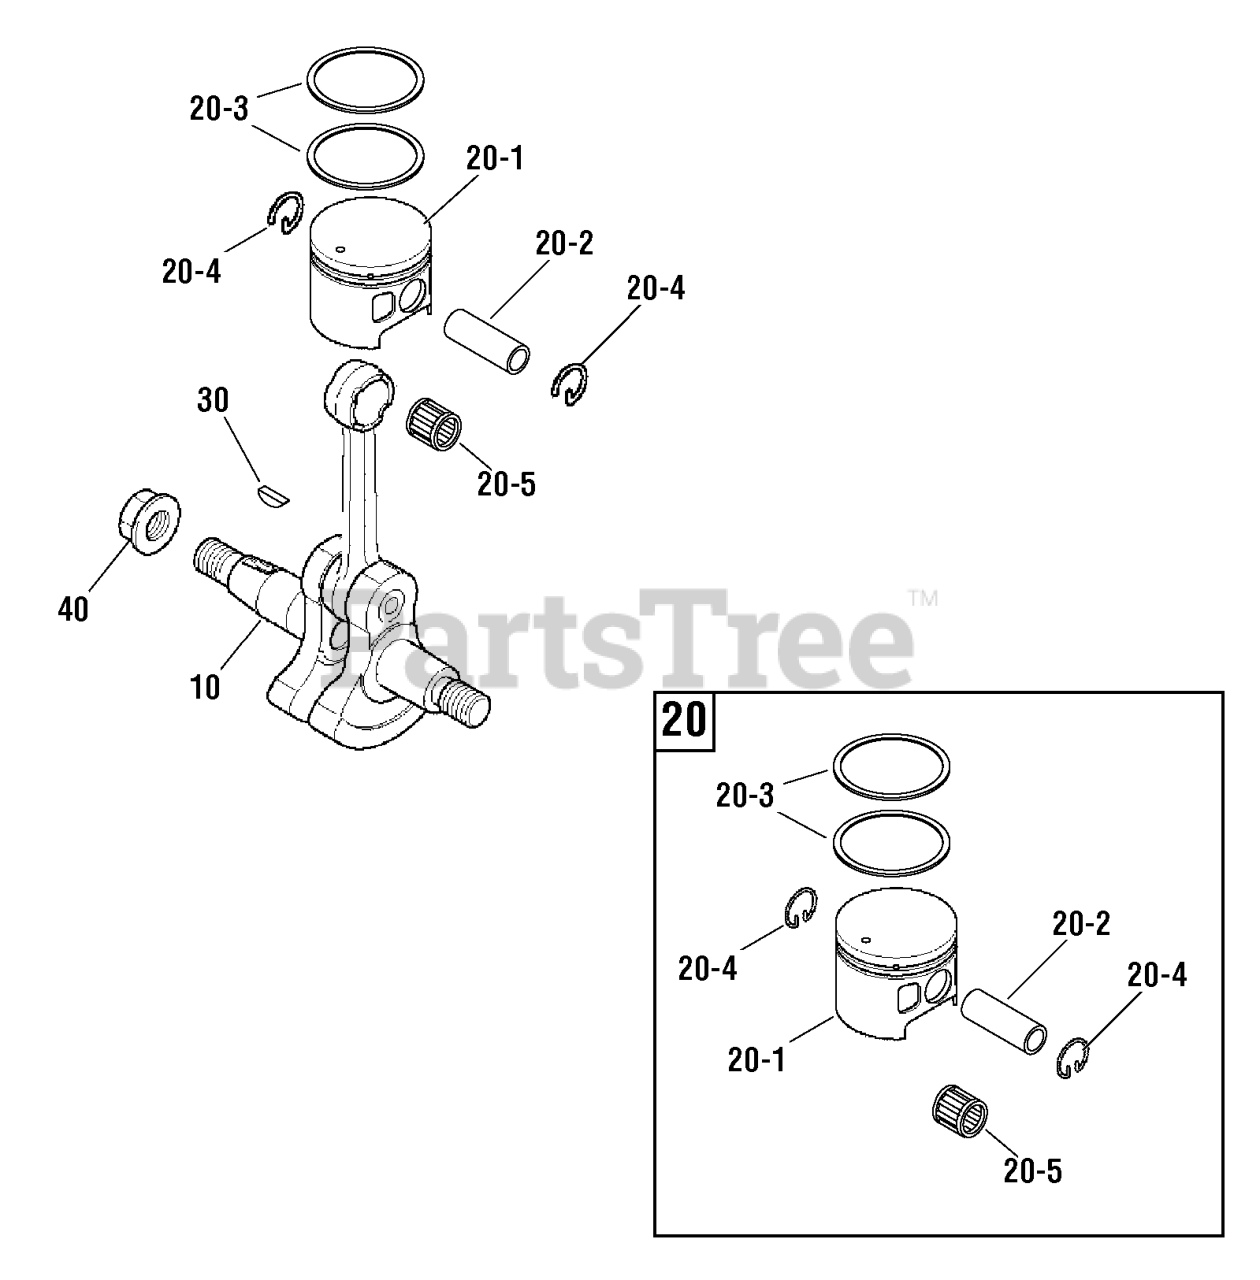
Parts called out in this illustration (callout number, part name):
10	CRANKSHAFT ASSEMBLY
20	PISTON & RING ASSEMBLY
20-1	PISTON
20-2	PIN, Piston
20-3	RING, Top
20-4	CLIP, Piston Pin
20-5	BEARING, Needle
30	KEY, Woodruff
40	NUT
